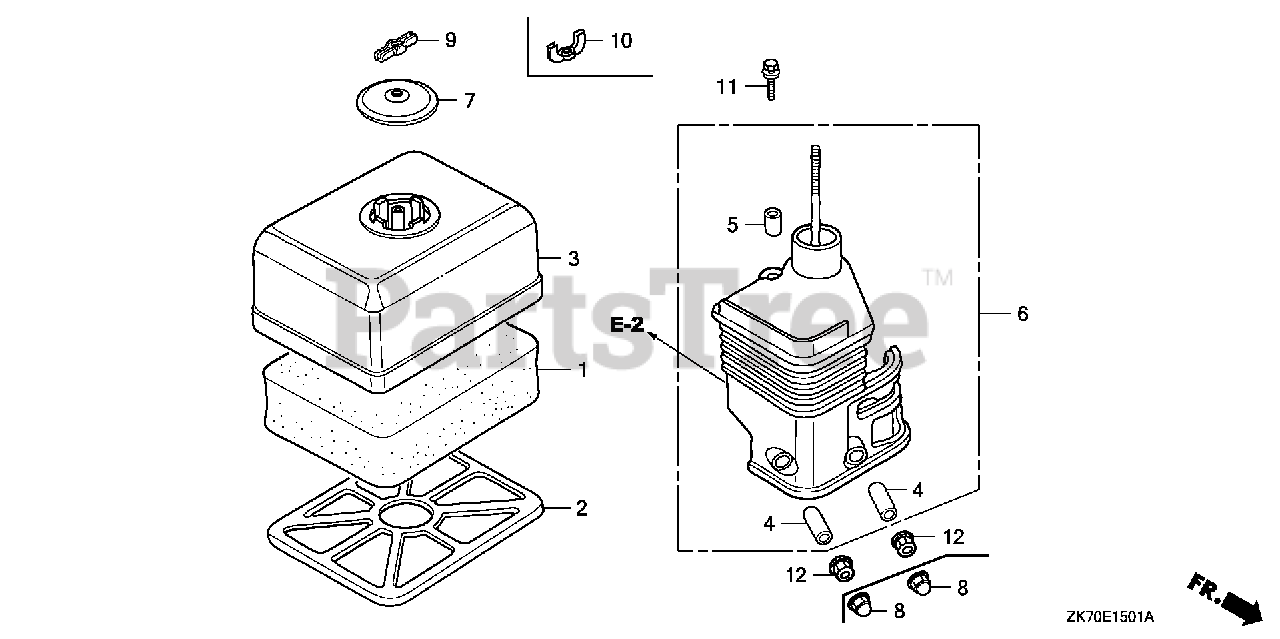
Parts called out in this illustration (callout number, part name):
1	ELEMENT, AIR CLEANER (SEMI-DRY)
2	GRID, AIR CLEANER (SEMI-DRY)
3	COVER, AIR CLEANER (SEMI-DRY)
4	COLLAR, AIR CLEANER
5	COLLAR B, AIR CLEANER
6	ELBOW, AIR CLEANER
7	CAP, CLEANER
10	NUT, TOOL BOX SETTING
11	BOLT, FLANGE (6X20)
12	NUT, FLANGE (6MM)
